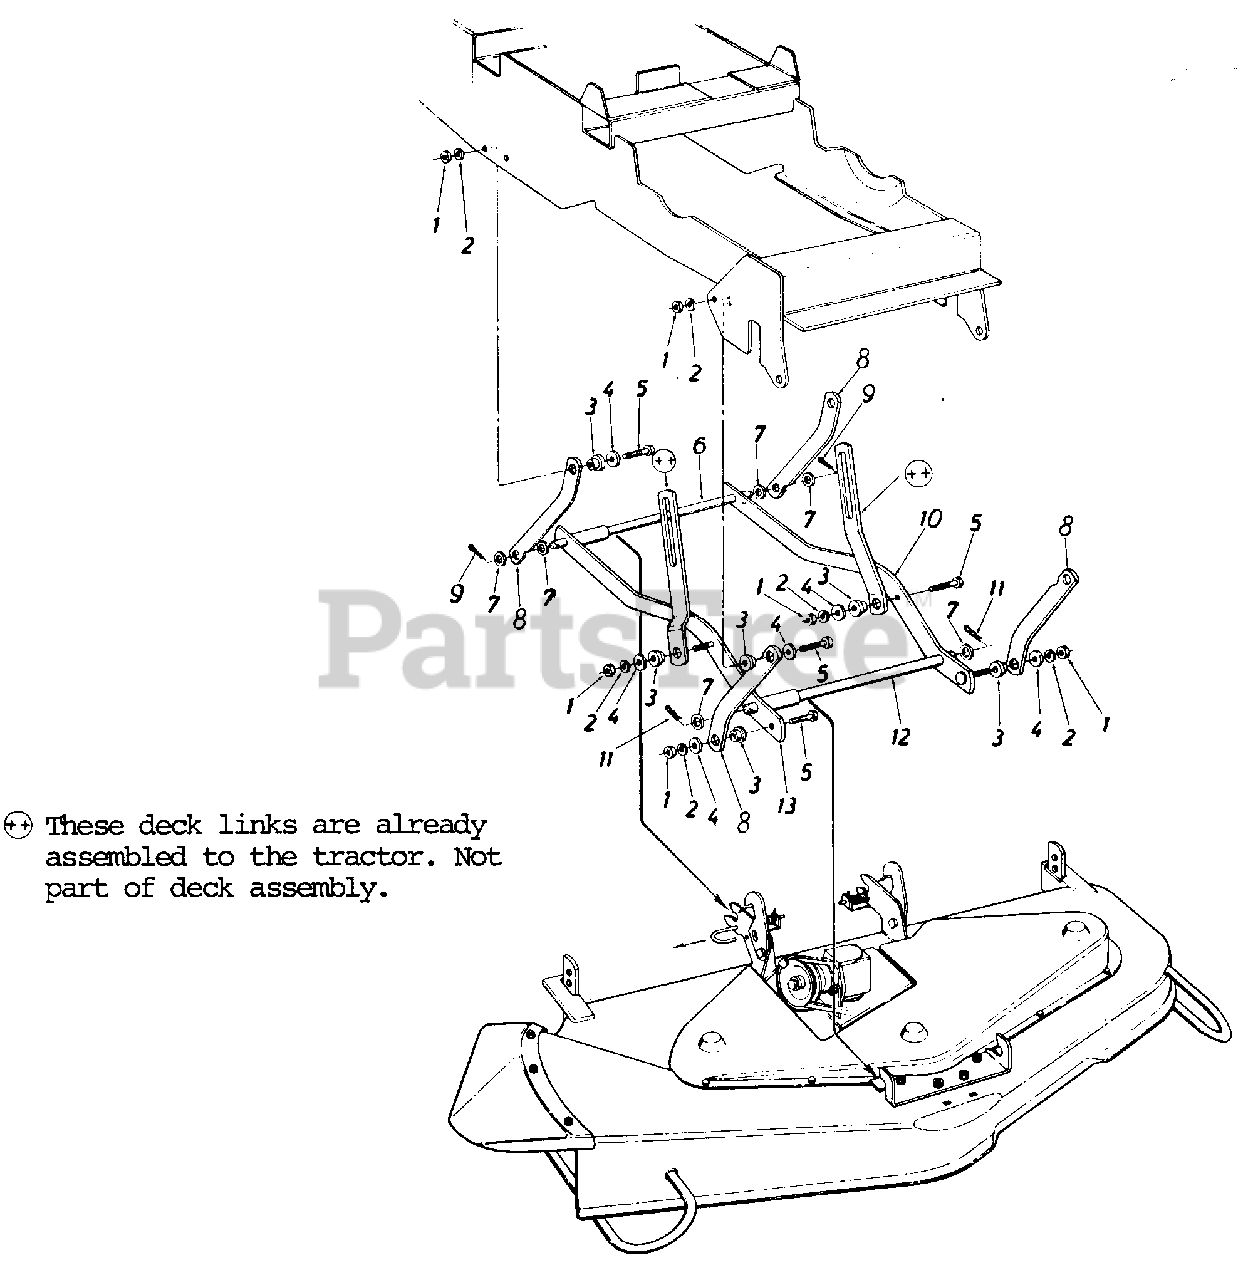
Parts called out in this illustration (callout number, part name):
1	Hex Nut 3/8-24 Thd.*
2	L.-Wash. 3/8" Scr. Heavy Duty*
3	Shoulder Spacer
4	Fl.-Wash. 3/8" I.D. x 1.0" O.D.
5	Hex Scr. 3/8-24 x 1.50" Lg. Grade 5
6	Cross Shaft Ass'y.-Rear
7	Fl.-Wash. 5/8" I.D. x 1-1/8" O.D.
8	Lift Arm
9	Cotter Pin 5/32" Dia. x 1.25" Lg.
10	Lift Arm Link-L.H.
11	Hair Pin Cotter
12	Cross Shaft Ass'y.-Front
13	Lift Arm Link Ass'y.-R.H.
